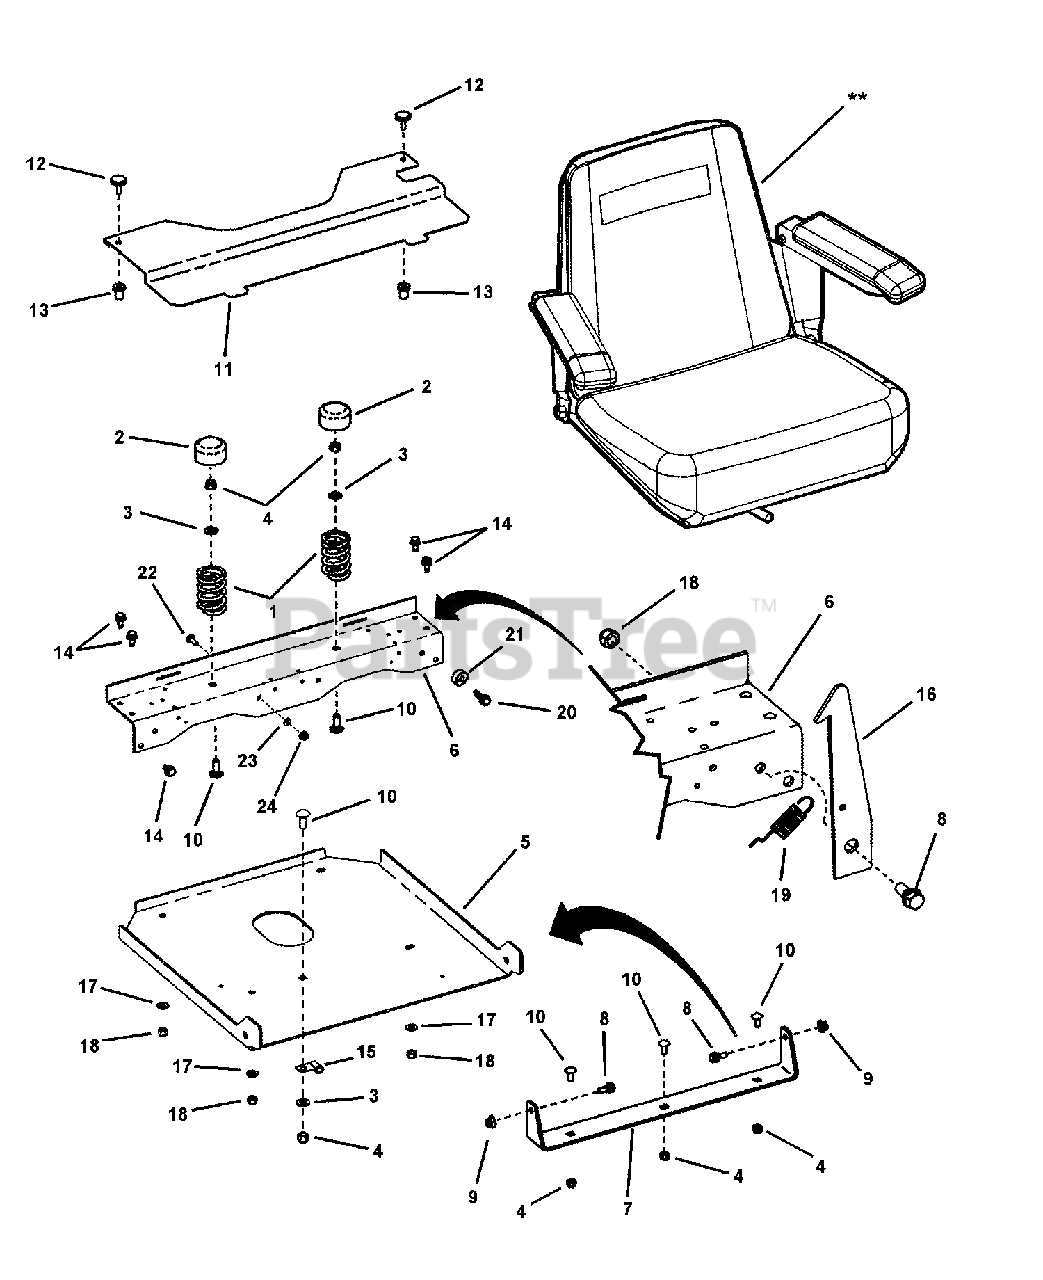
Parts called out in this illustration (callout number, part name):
1	SPRING, Compression- Seat Support
2	COVER, Seat Support Spring
3	WASHER, 3/8" Flat
4	NUT, 3/8-16 HEX NYLON LOCK
6	CROSSMEMBER, Seat
7	PIVOT BRACKET, Seat Hinge
8	SHOULDER BOLT, 5/16-18
9	NUT, 5/16-18 Large Flange Hex Center Lock
10	BOLT, 3/8-16 x 1" Square Neck Carriage GR5
11	GUARD, Fan
12	KNOB, 1/4-20 x 3/4" Thread
13	WELL-NUT, 1/4-20 x 53/64"
14	SCREW, 5/16-18 x 5/8" Hex Washer Self-Tap
15	CLIP, Open J 3/8 Cushioned
16	LATCH, Seat
17	WASHER, 5/16" Flat
18	NUT, 5/16-18 HEX NYLON LOCK
19	SPRING, Extension
20	SCREW, 5/16-18 x 3/4" Hex Washer self-Tap
21	SPACER, .340 I.D.x .63 O.D. x .310 Thick
22	BOLT, 1/4-20 x 3/4" Short Neck Carriage, GR5
23	RETAINER, 1/4" Bolt
24	NUT, 1/4-20 Hex Flange Lock
